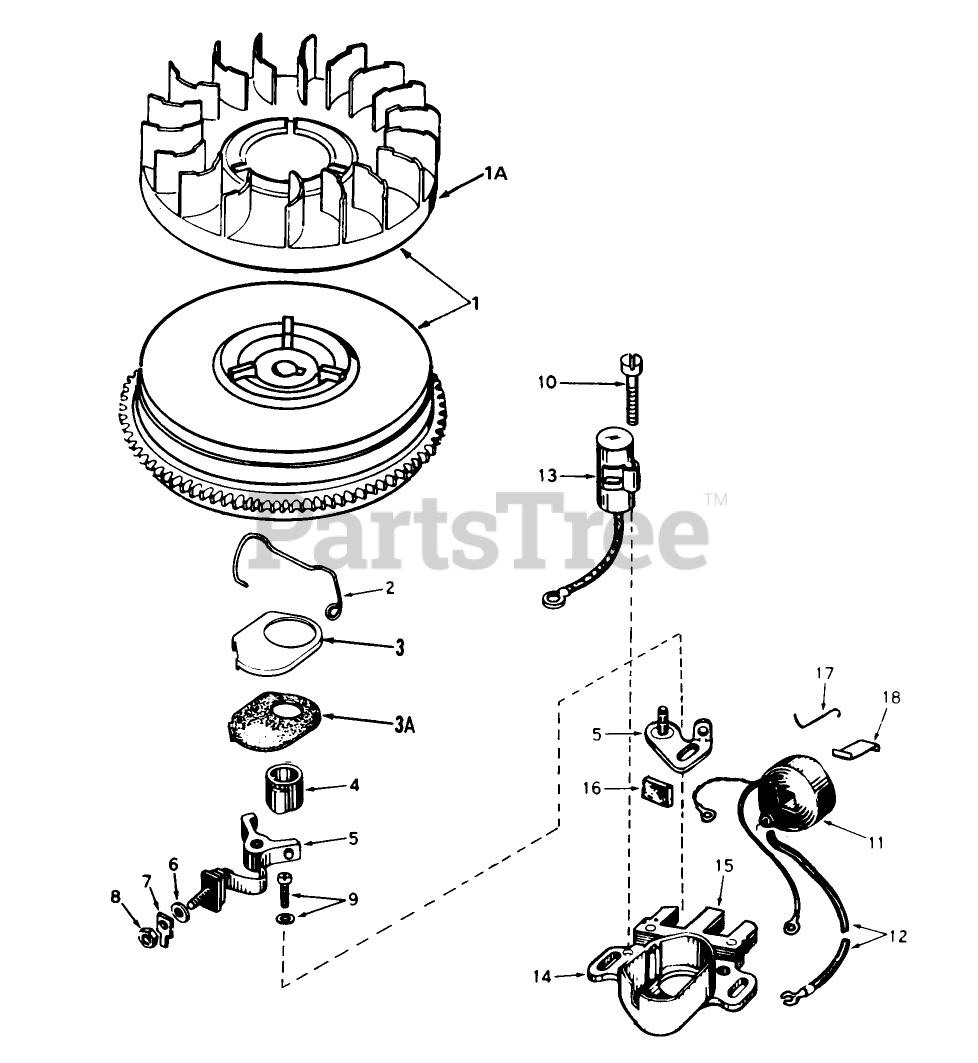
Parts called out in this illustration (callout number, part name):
1	Flywheel (Incl. Nos. 1A, 3 3A)
2	Spring Breaker Box
3	Cover-Dust
3A	Gasket, Dust Cover
4	Cam-Breaker
5	Breaker Assy.
6	Washer
7	Terminal, Ground
8	DECAL
9	Breaker Screw
10	Condenser Screw
11	Coil Assy. (Incl. No. 12)
12	Wire, Lead
13	Condenser
14	Core Plate
15	Stator Assy. (Incl. Ref. #2 thru 11, 13, 14, 16, 17 19)
16	Felt,Cam Wiper
17	Clip, Coil
18	Spring Coil Wedge
